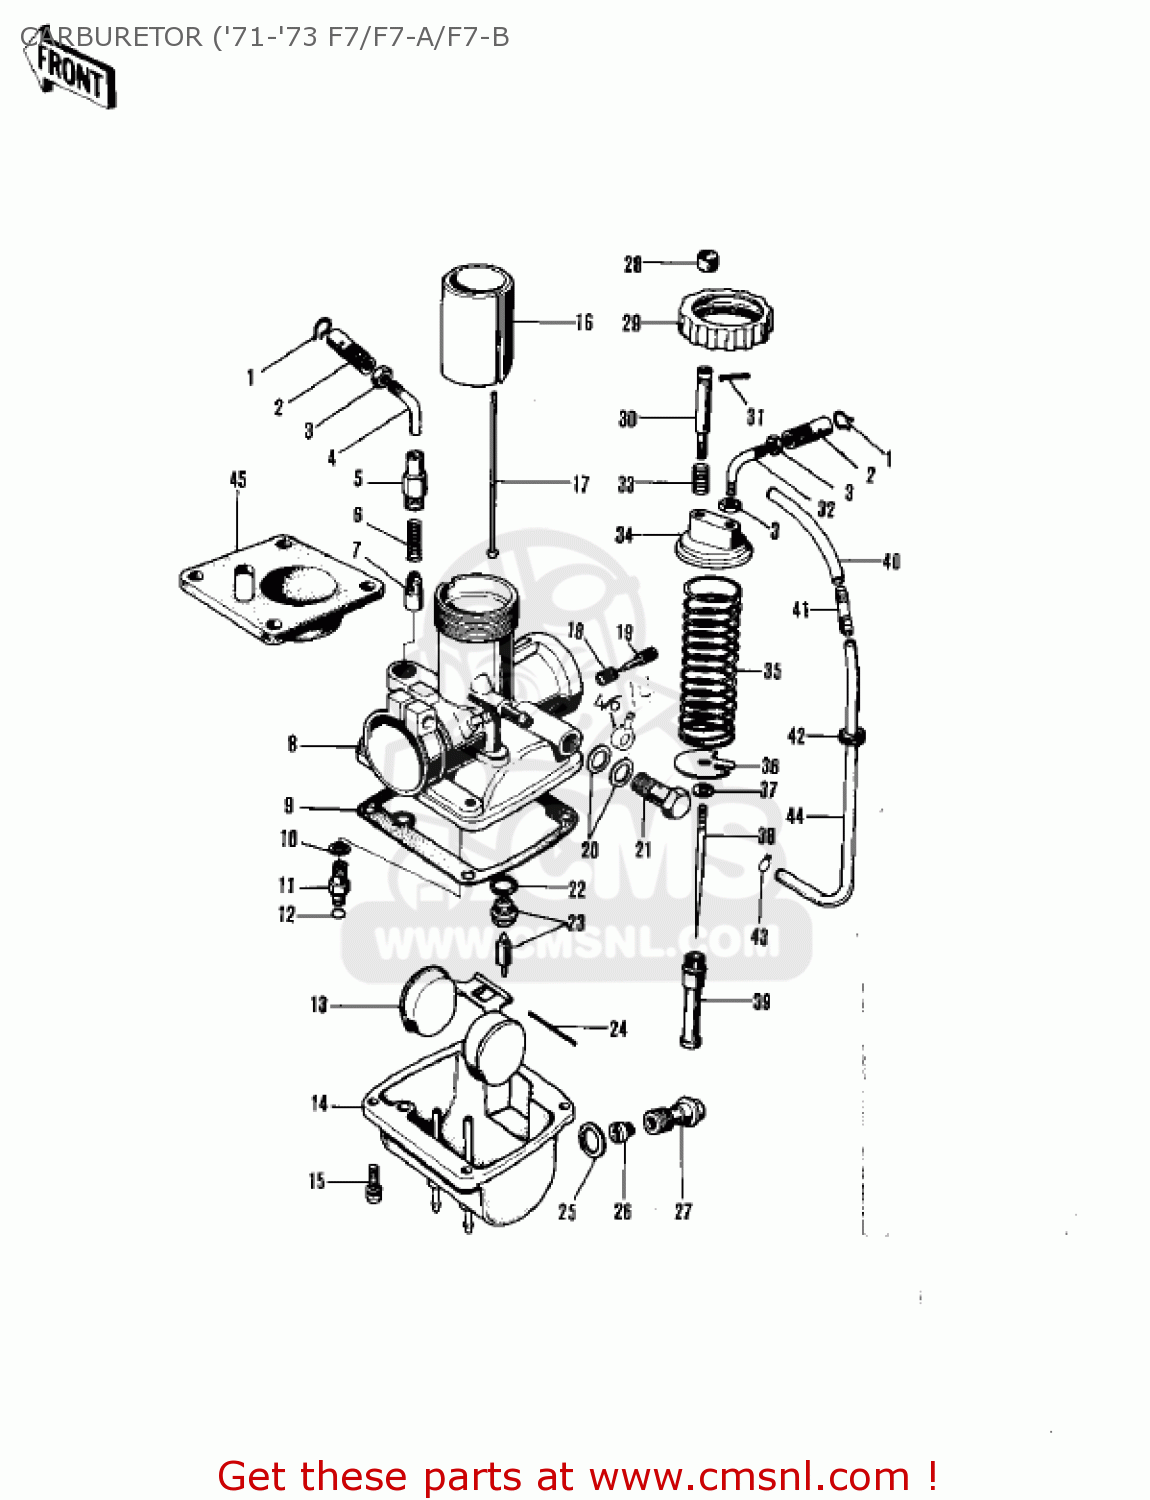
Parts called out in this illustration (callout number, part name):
1	CIRCLIP
2	ADJUSTER-CABLE,THROTT
3	NUT-CABLE ADJUST LOCK
4	CABLE GUIDE
5	CAP-STARTER PLUNGER
6	SPRING-STARTER PLUNG
7	PLUNGER,STARTER
9	GASKET-FLOAT CHAMBER (NAS)
10	WASHER-MAIN JET
11	HOLDER,JET NEEDLE
12	'O' RING
13	FLOAT
15	SCREW-FLOAT CHAMBER
16	VALVE,THROTTLE CA2.5
17	ROD-THROTTLE VLV STOP
18	SPRING-THR STOP SCREW
19	SCREW-PILOT AIR
20	GASKET,8MM
21	BOLT-BANJO
22	WASHER-FLOAT VLV SEAT
23	VALVE-FLOAT,2.5
24	FLOAT PIN
25	WASHER,BANJO BOLT (MCA)
26	JET-MAIN,#A110
27	BOLT-BANJO
28	CAP,PILOT SCREW
29	CAP-MIXING CHAMBER
30	SCREW-THROTTLE STOP
31	PIN-COTTER,1.2X10
32	GUIDE,CABLE
33	SPRING-THR STOP SCREW
34	TOP-MIXING CHAMBER
35	SPRING-THROTTLE VALVE
36	SPRING SEAT,THRTL VL
37	CLAMP,E-TYPE
38	NEEDLE-JET,4EJ3
39	JET,NEEDLE,#0-2
40	PIPE-OIL TANK
41	NIPPLE
42	GROMMET,PIPE
43	CLAMP-FUEL PIPE
44	PIPE
45	CAP-CARBURETOR
46	CONNECTOR,BANJO
?	CARBURETOR ASSEMBLY
